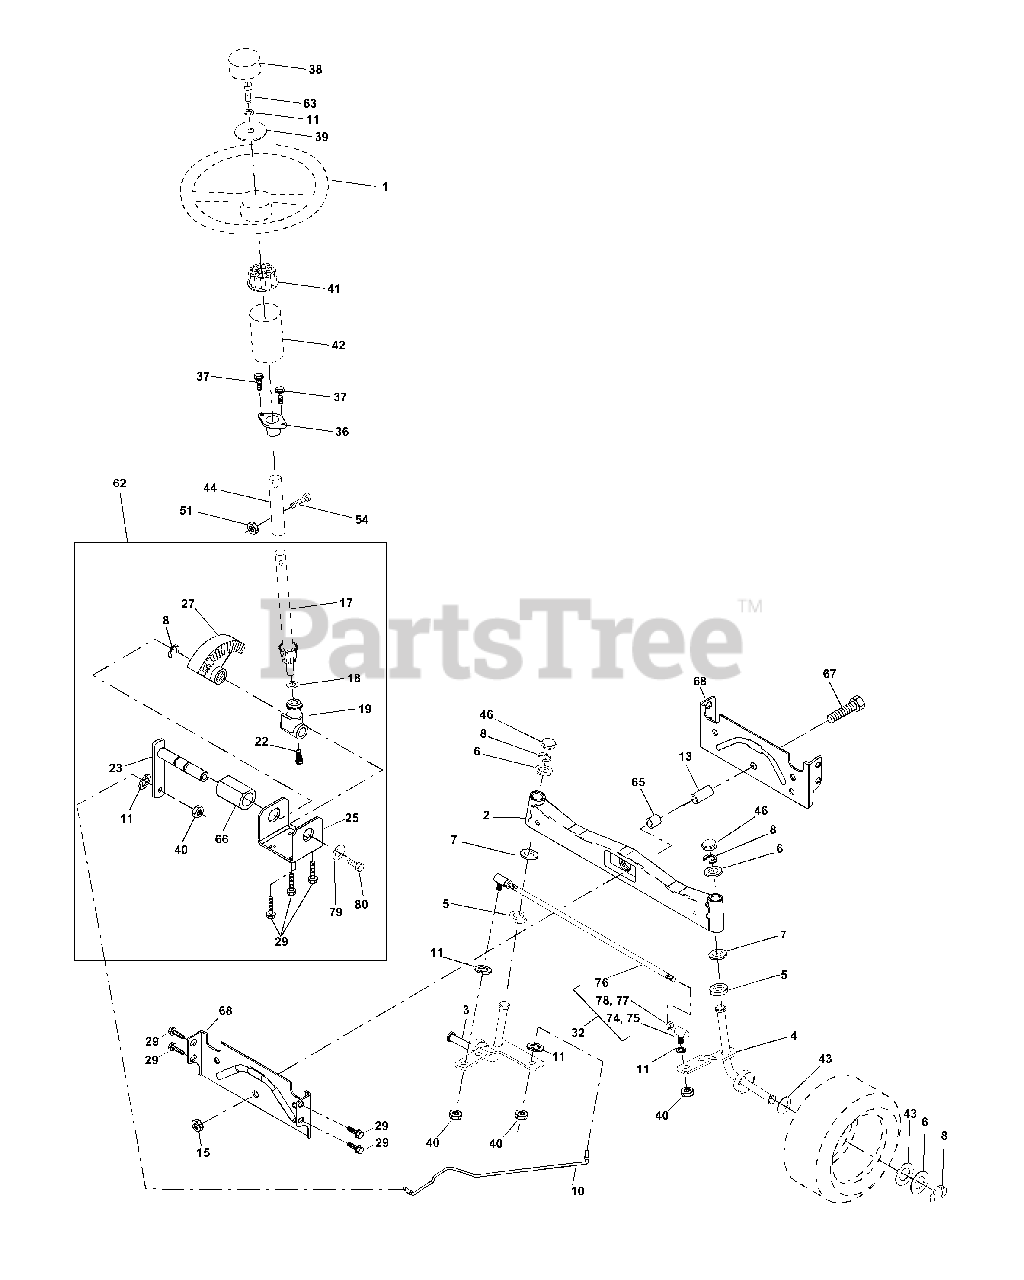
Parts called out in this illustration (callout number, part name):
1	Wheel Steering
2	Axle Asm Cast Iron LT
3	Spindle Asm LH
4	Spindle Asm RH
5	Bearing Race Thrust Harden
6	Washer 25/32 X 1-5/8 X 16 Ga
8	Ring Klip #t5304-75
10	Link Drag
11	Washer Lock Hvy Hlcl Spr 3/8
13	Spacer Brg Axle Front
15	Nut Hex Flange Lock
17	Shaft Asm Strg
18	Washer Thrust 515x 750x 033
19	Support Shaft
22	Screw Hex Wsh Hd Torx
23	Shaft Asm Pittman
25	Bracket Steering
27	Gear Sector
29	Screw 3/8-16 x .75
32	Rod Tie
33	Washer 11/32 x 3/4 x 16 Ga
34	Washer Lock Hvy Hlcl Spr 5/16
35	Crownlock Nut 5/16-24 Unf
36	Bushing Strg
37	Screw
38	Insert Cap Strg Wh
39	Washer 13/32 X 1-1/20 X 11 Ga
40	Lock nut
41	Adaptor Wheel Strg
42	Boot Steering Dash
43	Washer 25/32 X 1 1/4 X 16 Ga
44	Extension Steering Shaft LR/LT
46	Cap Spindle Fr Top Blk
51	Nut Lock Hex w/Ins 5/16-18
54	Bolt Fin Hex 5/16-18 Unc x 1-1/4
62	Kit, Steering Assembly Svc
63	Bolt Fin Hex 3/8-16unc x 1 Gr. 5
65	Spacer Brace Axle
66	Bearing Arm Pittman
67	Bolt Rdhd Sq 3/8-16 Unc x 2-3/4
68	Axle, Brace
79	Washer 13/32 x 1-1/4 x 12 Ga.
80	Bolt Hex Nylon 3/8-16 x 3/4
82	Bracket Susp Chassis Front
87	Washer Flat .781 x 1-1/2 x .14
